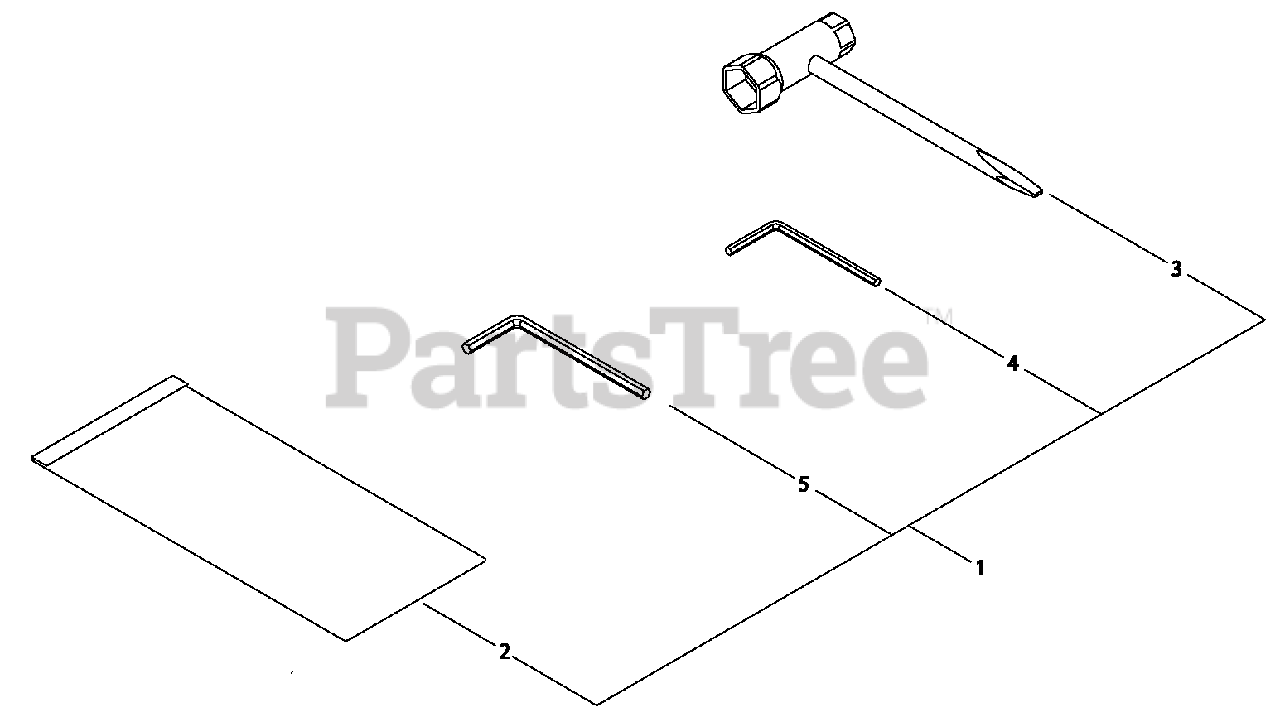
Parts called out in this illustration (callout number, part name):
1	TOOL KIT
2	T-WRENCH - 17X19mm
3	HEX KEY - 4mm
4	HEX KEY - 6mm
5	BAG, TOOL
